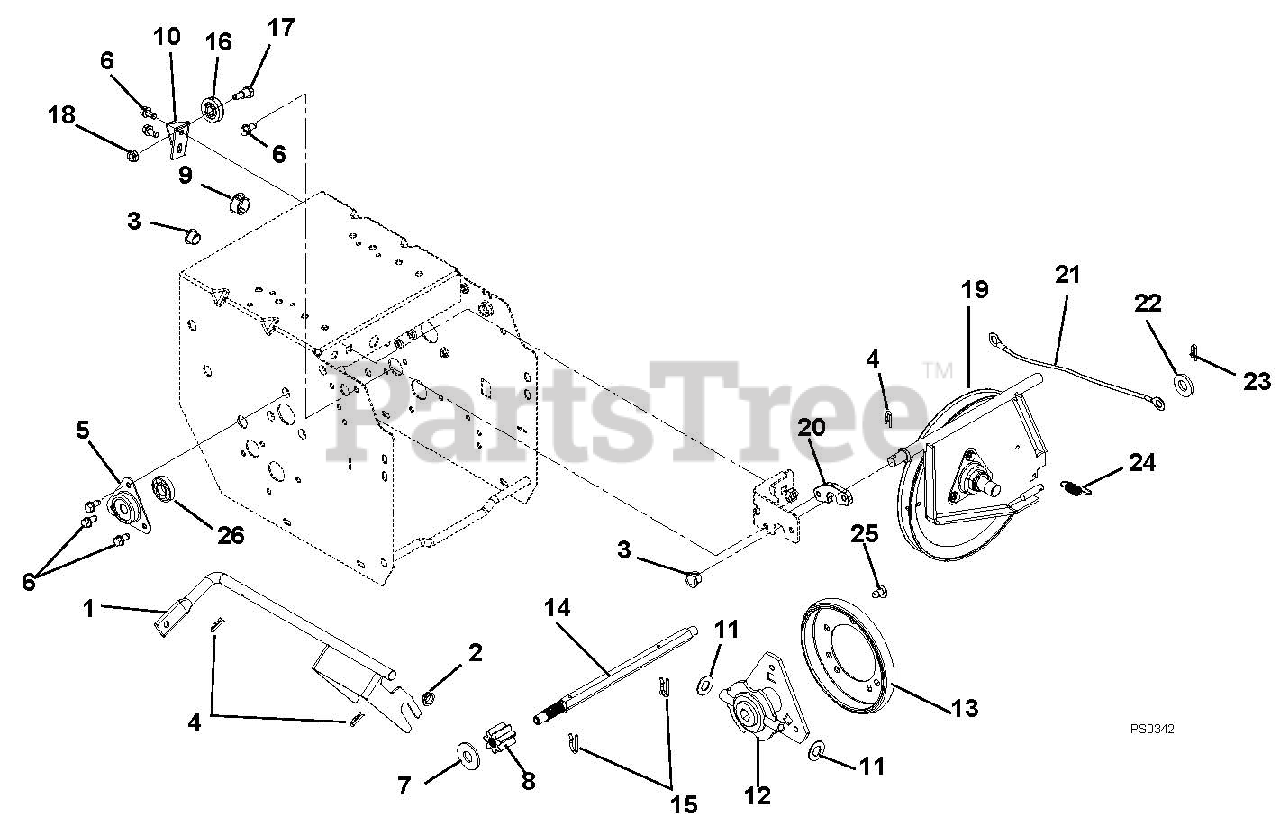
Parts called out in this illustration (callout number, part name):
1	WELDMENT, SHIFT FORK
2	BUSHING, POLYLINER-.50 SNAPIN
3	BUSHING, POLYLINER-.50 SPLIT
4	CLIP, SPRING
5	FLANGE, BEARING
6	SCR-TAP .25-20X.50 HWH TR YWZ
7	@WSHR-FL-STL.563X1.38X.109YWZC
8	GEAR, PINION, 7 TOOTH W/SPLINE
9	PLUG, HOLE - .875" NYLON
10	BRACKET, CABLE PULLEY
11	WSHR-FL-STL .505X1.00X.062YWZC
12	CARRIER, DRIVE DISK
13	FRICTION, DISC
14	SHAFT, HEX W/SPLINE
15	PIN, SPRING CLIP
16	PULLEY, CABLE
17	BOLT, SHLDR-.375X.375X.25-20
18	@NUT-LK-TOP-FLG .25-20 YWZC
19	PLATE, SWING - ASSEMBLY
20	SPACER, SWING GATE
21	CABLE, TRACTION - TRACTOR
22	@WSHR-FL-STL.344X.688X.065YWZC
23	PIN-HAIR INT .08X.18X1.18 YWZC
24	SPRING, EXT. .043X.438X1.64
25	SCR-TAP SERRDHDTX .31-18X.50BP
26	BRG-BALL .437X1.375X.437
